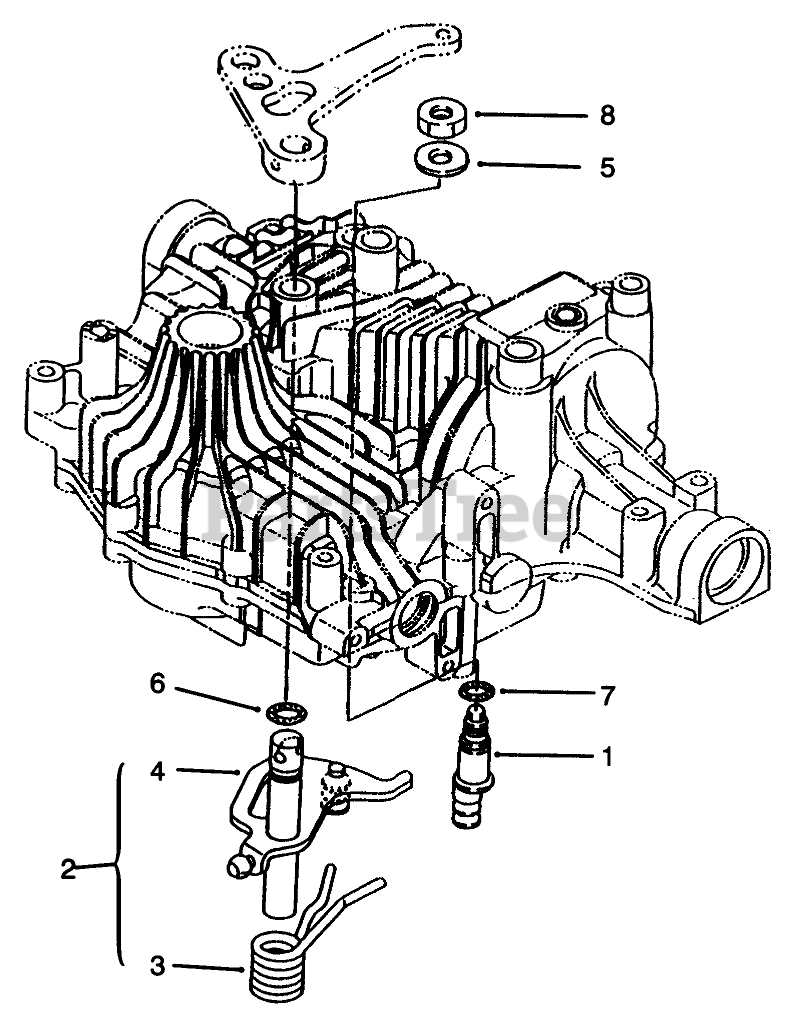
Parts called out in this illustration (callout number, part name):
1	Fulcrum (Only On: 72043, 72063, 72103)
2	Shaft ASM INCL 3-4(Only On: 72043, 72063, 72103)
5	Washer (Only On: 72043, 72063, 72103)
6	Packing (Only On: 72043, 72063, 72103)
7	Packing (Only On: 72043, 72063, 72103)
8	Nut (Only On: 72043, 72063, 72103)
